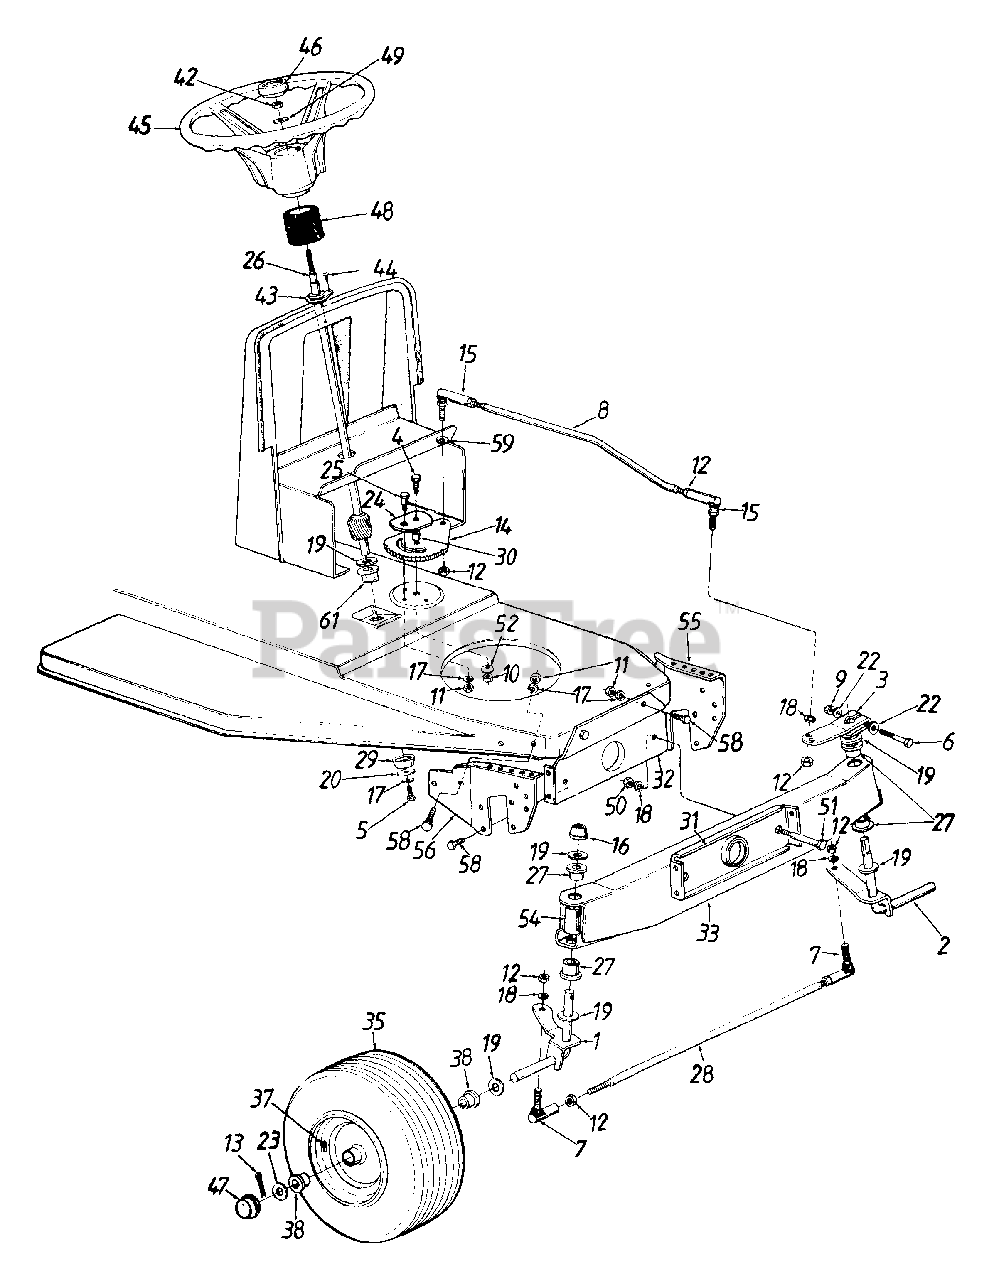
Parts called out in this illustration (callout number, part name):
1	Front Axle Ass'y.- R.H.
2	Front Axle Ass'y.- L.H.
3	Steering Arm
4	Hex Bolt 3/8-24 x 1" Lg.
5	Hex Bolt 5/16-18 x .62"
6	Hex Bolt 5/16-24 x 2" Lg.
7	Ball Joint 3/8-24 Thd.
8	Steering Drag Link
9	Hex L-Nut 5 16-24 Thd.
10	Hex Nut 3/8-24 Thd.
11	Hex Nut 5/16-18 Thd.
12	Hex Jam Nut 3/8-24 Thd.
13	Cotter Pin 1/8 Dia.
14	Steering Gear Segment
15	Drag Link Ball Joint 3/8-24 Thd.
16	Push Cap
17	L-Wash. 5/16" I.D.
18	L-Wash. 3/8" I.D.
19	Fl-Wash..64" I.D. x 1.24"
20	Fl-Wash..340" I.D. x 1.125"
22	Spr. Wash..32" I.D. x.62"
23	Fl-Wash..635" I.D. x 1.585"
24	Retainer Plate
25	Shld. Bolt .437" Dia. x .350"
26	Steering Shaft
27	Hex Flange Brg..632" I.D.
28	Tie Rod 20" Lg.
29	Spacer .985" I.D.
30	Spacer .380" I.D.
37	Air Valve
38	Bearing
42	Hex L-Nut 5/16-24 Thd.
43	Steering Column Brg.
44	Cr-Sunk Scr. #10 x 5/8" Lg.
45	Steering Wheel
46	Steering Wheel Cap
47	Hub Cap
48	Bellow Steering Column
49	Bell-Wash..345" I.D. x .88"
50	Hex Nut 3/8-16 Thd.
51	Shld. Bolt 1/2" Dia. x 2.04"
52	Bell-Wash..39" x 1.38" O.D.
54	Plastic Tube
55	Pivot Bar Side Plate - L.H.
56	Pivot Bar Side Plate - R.H.
58	Hex Wash. Tap Scr. 5/16-18 x .62" Lg.
59	L-Wash. 3/8" I.D. (H.D.)
61	Hex Flange Brg..634" Dia.
